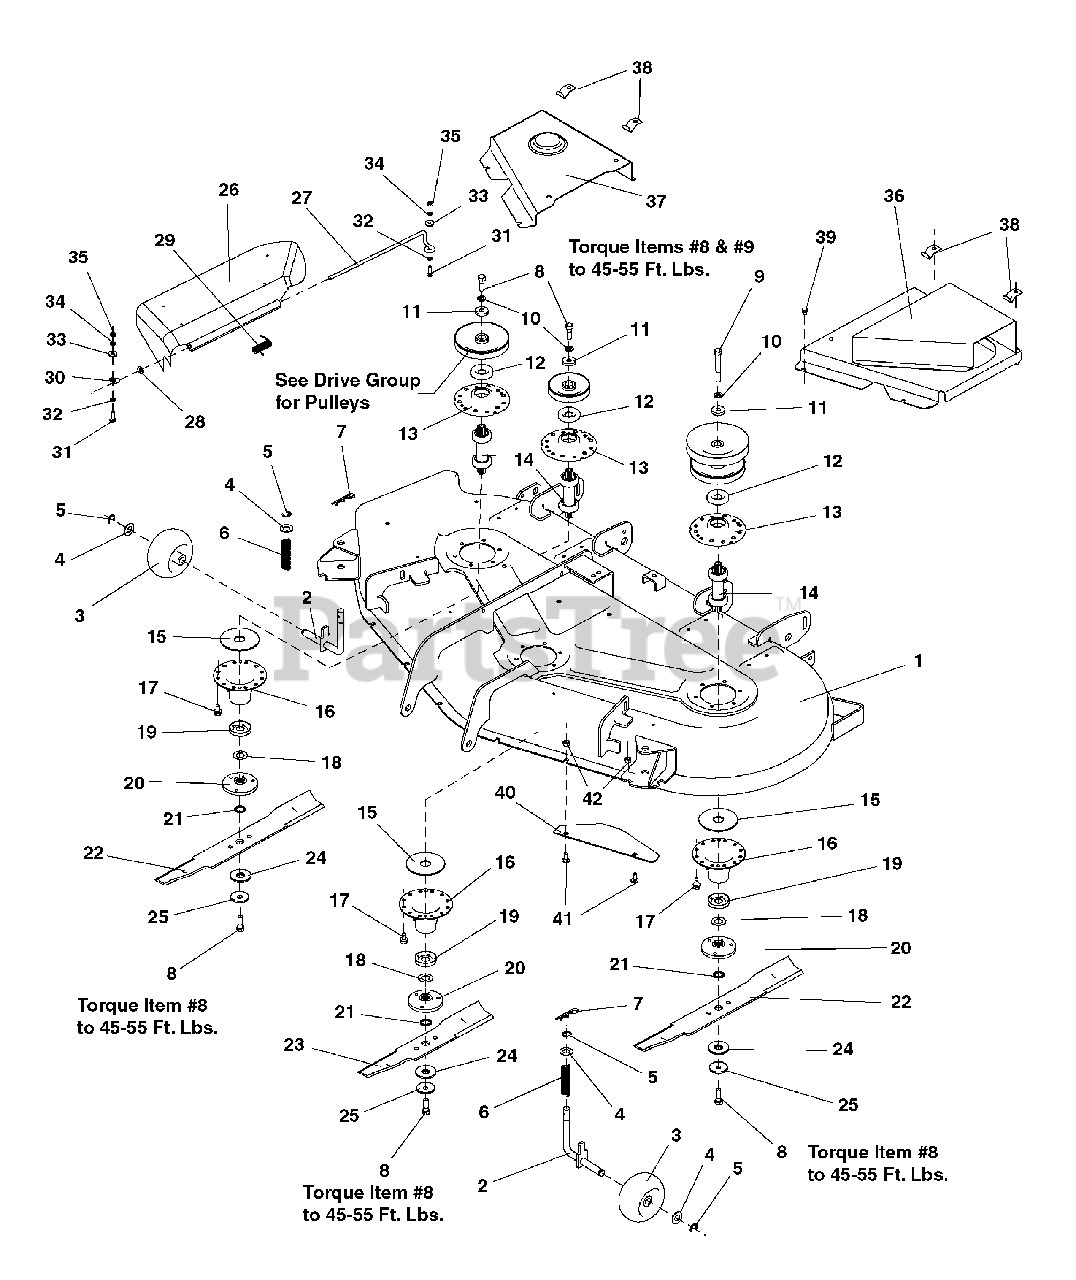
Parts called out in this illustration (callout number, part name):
1	HOUSING, 54" Mower
2	SPINDLE, Gauge Wheel
3	WHEEL, Gauge
4	WASHER, Plain, 5/8
5	KLIPRING, 5/8
6	SPRING, Compression
7	CLIP, Hair Pin
8	CAPSCREW, Hex Hd, 7/16-14 x 1-1/4
9	CAPSCREW, Hex Hd, 7/16-14 x 3-1/4
10	LOCKWASHER, 7/16
11	WASHER, 7/16
12	SHIELD, Bearing Upper, Arbor
13	ARBOR HOUSING, Top
14	ARBOR SHAFT & BEARING ASSEMBLY, Complete
16	ARBOR HOUSING
17	CAPSCREW, Hex Hd, Taptite, 5/16-18 x 3/4
18	WASHER, Shim
19	SHIELD, Grass
20	ADAPTER, Blade
21	RING, Self Locking
24	WASHER, Spline
25	WASHER, Spring
27	ROD, Deflector, Front
28	WASHER, 5/16
29	SPRING, Torsion
30	BRACKET, Hinge
31	CARRIAGE BOLT, 1/4-20 x 7/8
32	NUT, Push, 1/4
33	WASHER, 1/4
34	LOCKWASHER,1/4
35	NUT, Hex, 1/4-20
36	COVER, Arbor, LH
37	COVER, Arbor, RH
38	CLIP, Spring
39	CAPSCREW, Hex Hd, Taptite, 1/4-20 x 3/8
40	BAFFLE, Front
41	CARRIAGE BOLT, 5/16-18 x 3/4
42	NUT, Hex Flange, 5/16-18
